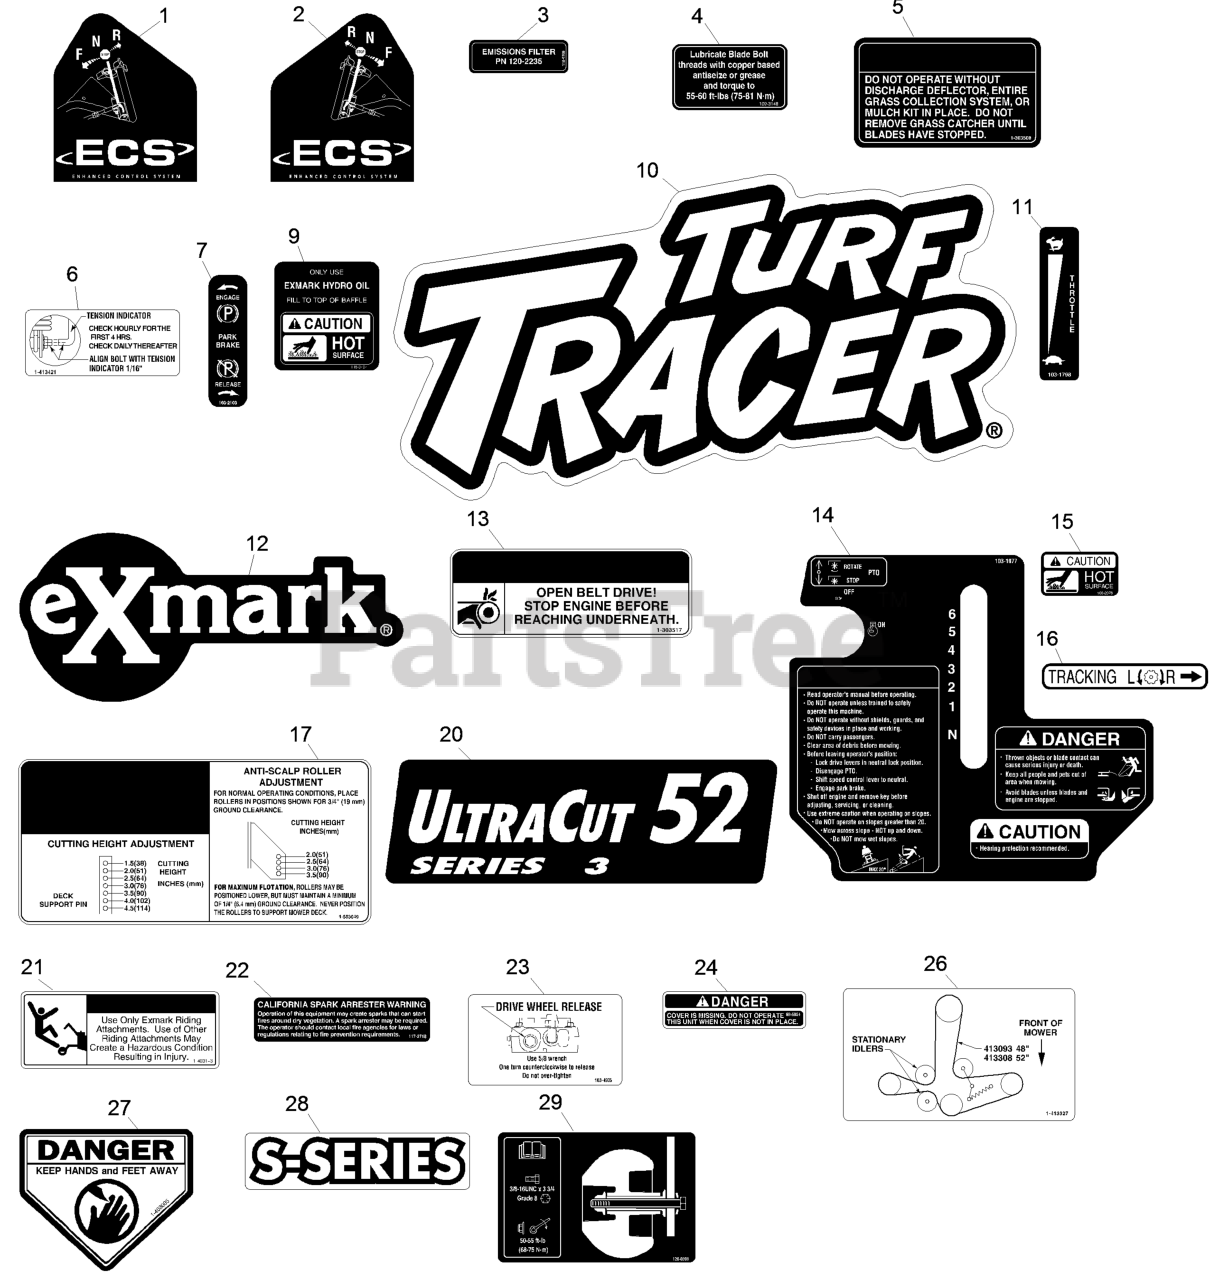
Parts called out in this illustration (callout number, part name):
1	DECAL,LH ECS INSTRUCTION
2	DECAL,RH ECS INSTRUCTION
3	DECAL-FILTER, EMISSIONS
4	DECAL,BOLT TORQUE
5	DECAL-WARNING, DISCHARGE
6	DECAL,INDICATOR
7	DECAL-BRAKE, PARK
9	DECAL-HYDRAULIC TANK
10	DECAL,TTH MODEL
11	DECAL,THROTTLE ONLY
12	DECAL,EXMARK LOGO
13	DECAL,BELT DRIVE
14	DECAL,ECS CONSOLE
15	DECAL-CAUTION
16	DECAL,TRACKING ADJUST
17	DECAL,ANTI SCALP
20	DECAL-ULTRACUT 52 SERIES
21	DECAL,SULKY WARNING
22	DECAL-ARRESTER, SPARK
23	DECAL,DRIVE RELEASE
24	DECAL-COVER, MISSING
26	DECAL,BELT ROUTING
27	DECAL-DANGER
28	DECAL-S-SERIES
29	DECAL-ROLLER MOUNTING
